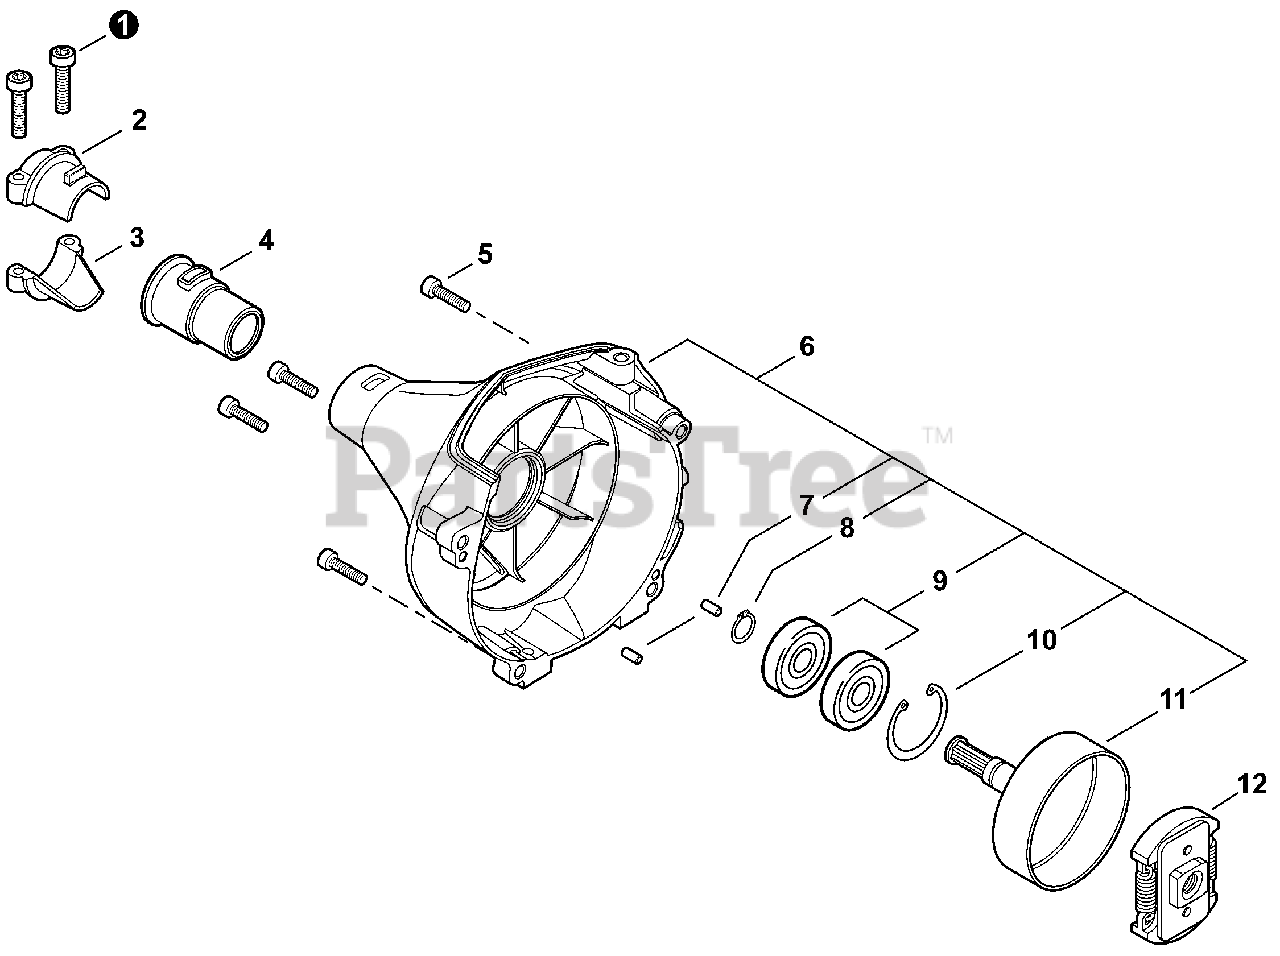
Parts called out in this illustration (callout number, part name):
1	BOLT, TORX 5×20
2	HOLDER, MAIN PIPE - UPPER
3	HOLDER, MAIN PIPE - LOWER
4	CUSHION Ø25
5	BOLT, TORX 4×16
6	COVER ASSY, FAN
7	PIN, LOCATING 4
8	RING, RETAINING - 12
9	BEARING, BALL 6001
10	RING, SNAP 28
11	DRUM, CLUTCH
12	CLUTCH ASSY
